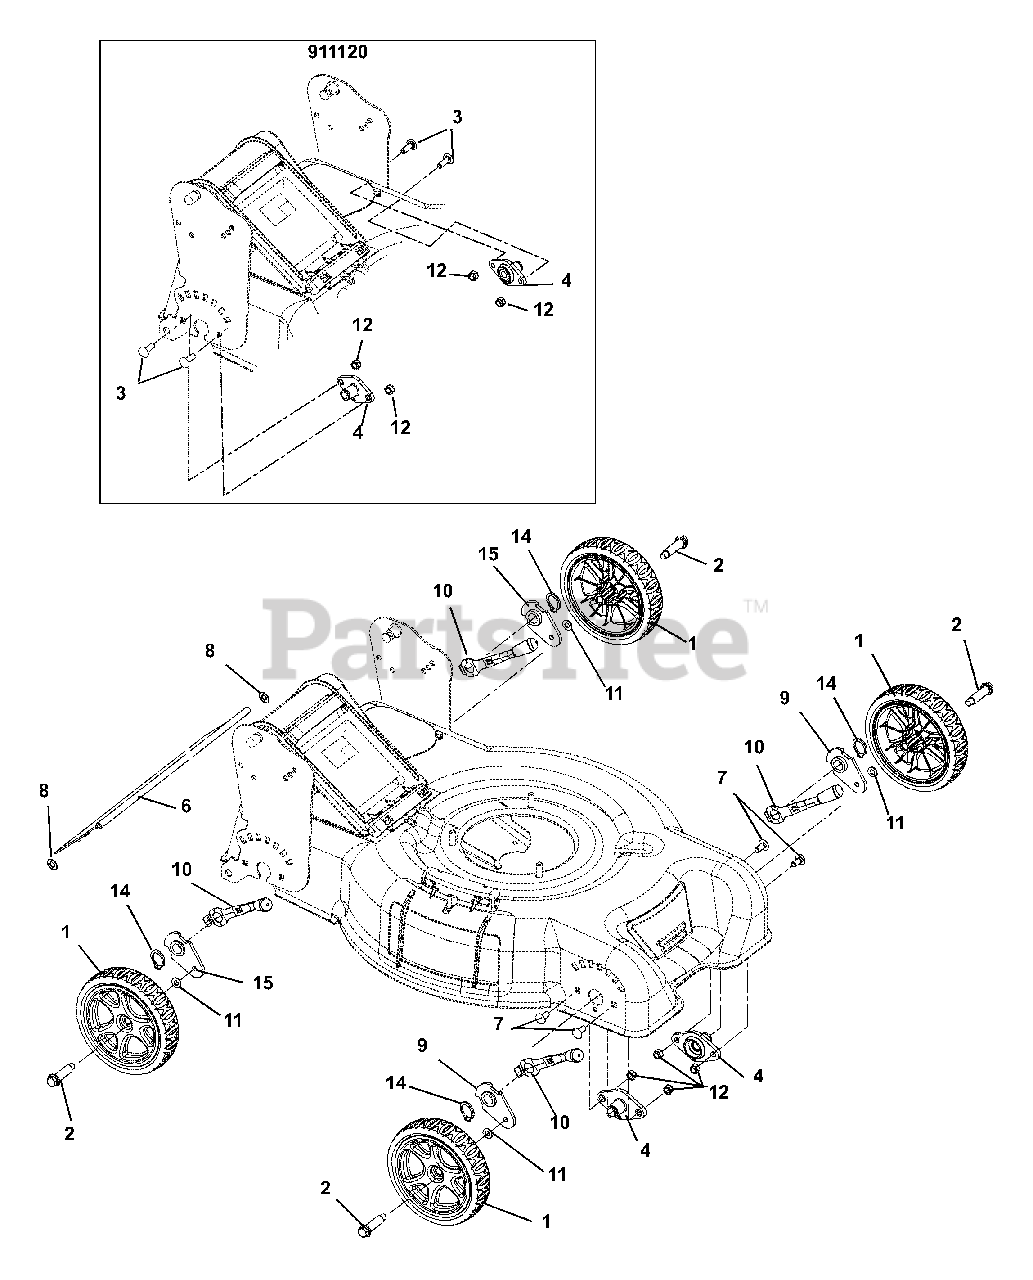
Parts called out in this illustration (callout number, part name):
1	Assembly, Wheel
2	Bolt, Wheel Shoulder
3	Bolt, Round Head Square Neck .31-18 x 1.00 Grade 5
4	Wheel Mount Hub
5	Wheel Mount Hub
6	Guard, WBLM
7	Bolt, Round Head Square Short Neck .31-18 x .75 Grade 5
8	Retainer, .38 Push-On
9	Weldment, Front Wheel Bracket
10	Height of Cut Lever
11	Washer, Flat Steel .406 x .812 x .065
12	Nut, Locking Top Flange .31-18
13	Nut, Locking Top Flange .31-18
14	Ring, Retaining-External .689 x .077
15	Weldment, Rear Wheel Bracket
